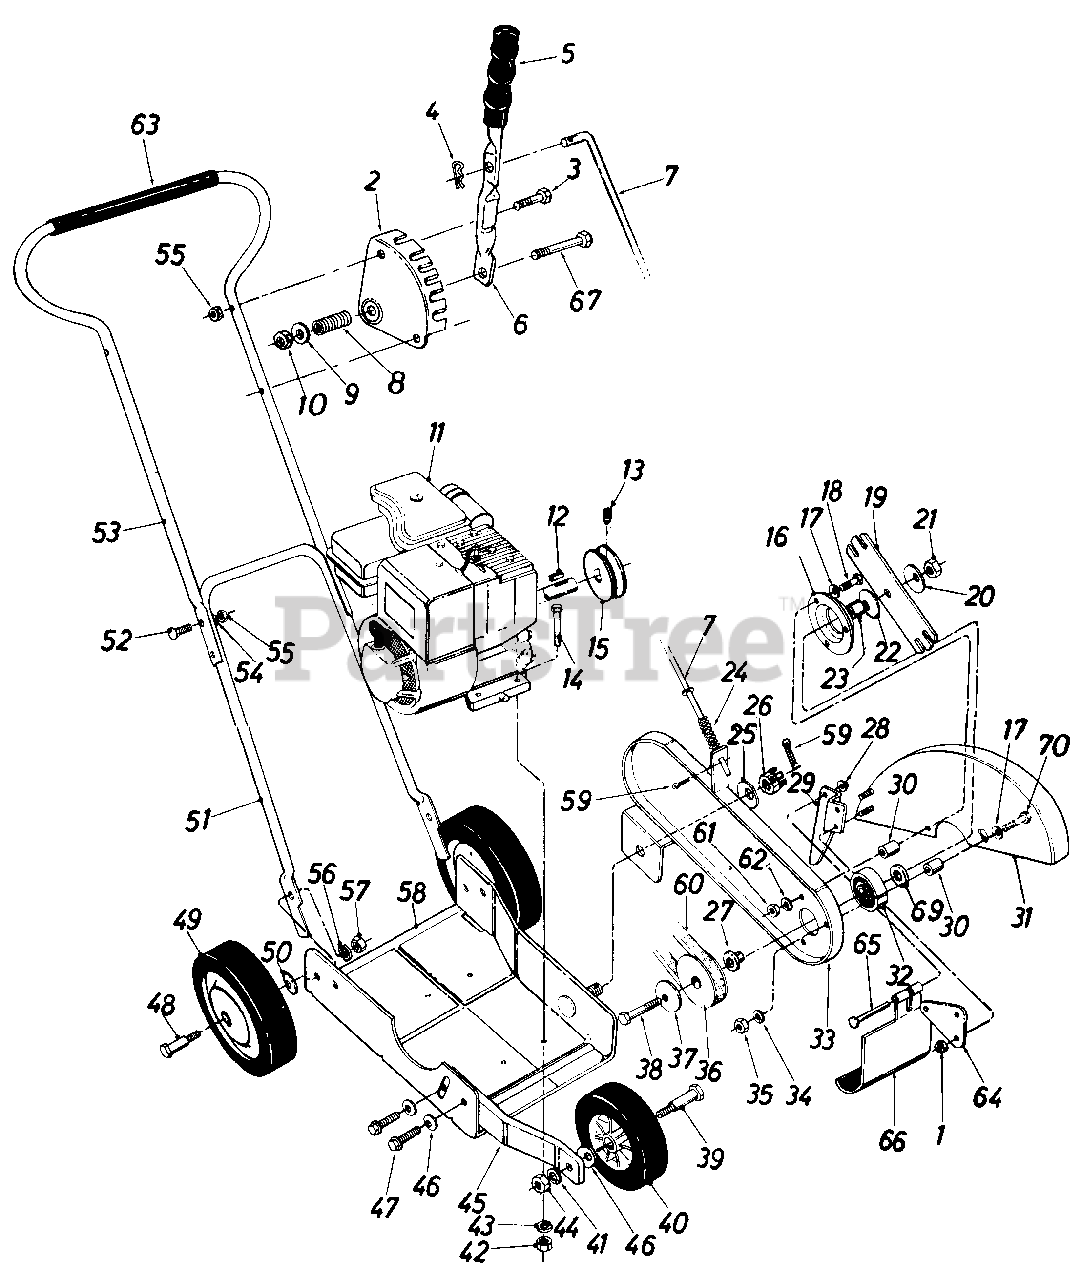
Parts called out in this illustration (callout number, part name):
1	Hex Cent. L.-Nut 1/4-20 Thd.
3	Hex Bolt 1/4-20 x 1.25" Lg.*
4	Cotter Pin 1/8" Dia. x 1.0" Lg.*
5	Grip
6	Clutch Handle
7	Clutch Rod
8	Compression Spring .50" O.D. x 1.38" Lg.
9	Fl.-Wash .34" I.D. x .62" O.D. x.063
10	Hex Cent. L.-Nut 5/16-18 Thd. Engine
11	Engine
12	Sq. Key 3/16 x 1.0" Lg.*
13	Set Scr. 1/4-28 x 1/4" Lg.
14	Hex Bolt 5/16-18 x 1.50' Lg.*
15	Engine Pulley
16	Bearing Housing
17	Bell.-Wash. .34" I.D. x 88" O.D. x .060
18	Hex Bolt 5/16-18 x 1.25" Lg.*
20	Bell.-Wash. .535" I.D. x 1.50" O.D. x.052
21	Hex Cent. L.-Nut 1/2-20 Thd.
22	Bell.-Wash. .535" I.D. x 1.50" O.D. x 052
23	Spacer
24	Compression Spring .57" O.D. x 1.92" Lg.
25	Bell.-Wash. .535" I.D. x 1.50" O.D. x .052
26	Hex Castle Nut 1/2-20 Thd.
27	Shoulder Spacer
28	Push Cap
29	Guide
30	Spacer .354" I.D. x.635" O.D. x .510" Lg.
33	Spindle Bracket Ass'y.
34	L.-Wash. 5/16" I.D.*
35	Hex Nut 5/16-18 Thd.
36	Pulley
37	Bell.-Wash. .535" I.D. x 1.50" O.D. x .052
38	Hex Bolt 1/2-20 x 3.50" Lg.*
39	Shoulder Bolt .498" Dia. x 1.450
40	Wheel Ass'y. Comp .6" Dia. x 1.50
41	L.-Wash. 3/8" I.D.*
42	Hex Nut 5/16-18 Thd.*
43	L.-Wash. 5/16" I.D.*
44	Hex Nut 3/8-16 Thd.*
45	Front Wheel Support
46	Bell.-Wash. .400" I.D. x 88" O.D. x .060
47	Hex Wash. Hd. Self Tap Scr. 3/8-16 x .75 " Lg.
48	Shoulder Bolt .498" Dia. x 1.450
49	Wheel Ass'y. Comp. 7" Dia. x 1.50
50	Bell.-Wash. .400" I.D. x 88" O.D.
51	Lower Handle
52	Carriage Bolt 1/4-20 x 1.25"-Lg.*
53	Upper Handle
54	L.-Wash. 1/4" I.D. *
55	Hex Nut 1/4-20 Thd.*
56	L.-Wash. 3/8" I.D.*
57	Hex Nut 3/8-16 Thd.*
58	Base Ass'y.
59	Cotter Pin 1/8" Dia. x 1.0"-Lg.*
60	3V-Belt 31.2" Lg.
61	Hex Nut 5/16-18 Thd.
62	L.-Wash. 5/16" I.D.*
63	Grip (Optional)
64	Flap Bracket
65	Hinge Pin
66	Debris Deflector
67	Hex Bolt 5/16-18 x 1.75" Lg. *
69	Fl.-Wash. .51 I.D. x 1.00 O.D. x.060
70	Hex Bolt 5/16-18 x 2.00" Lg.*
